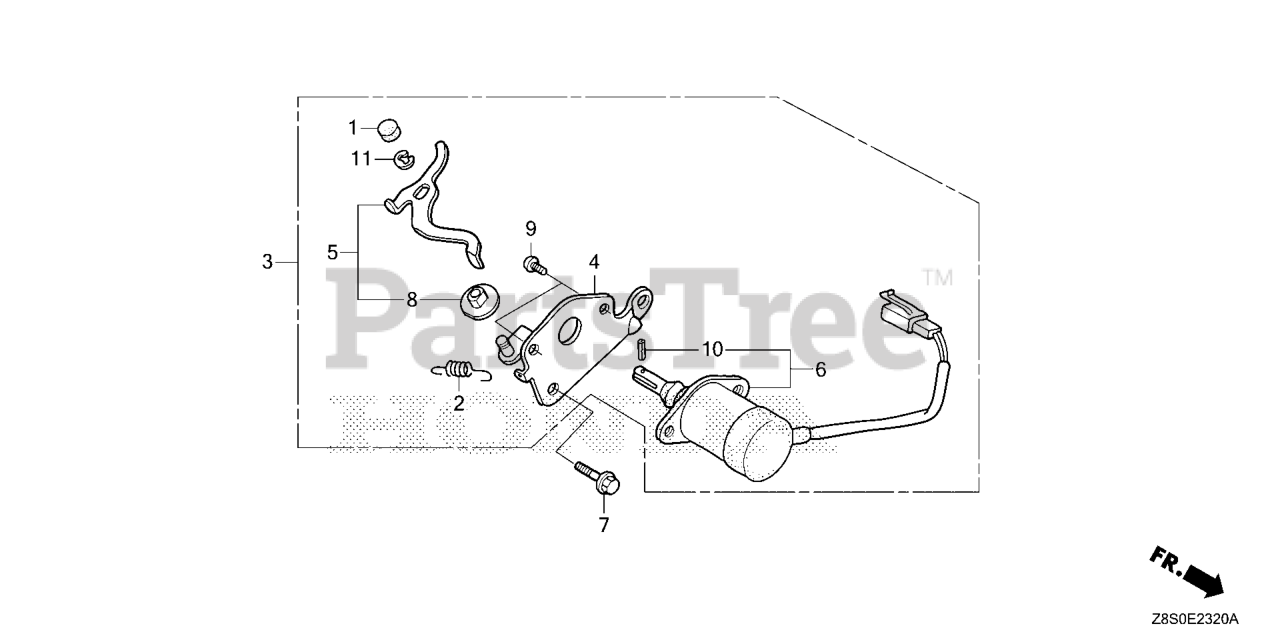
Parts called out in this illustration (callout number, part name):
1	CAP, CHOKE LEVER
2	SPRING, CHOKE RETURN
3	AUTO-THROTTLE ASSY.
4	STAY, SOLENOID THROTTLE
5	LEVER, SOLENOID THROTTLE
6	SOLENOID ASSY.
7	BOLT, FLANGE (6X12) (CT200)
8	BUSH, AUTO-THROTTLE LEVER
9	SCREW, PAN (5X8)
10	PIN, SPRING (2.5X16)
11	E-RING (4MM)
